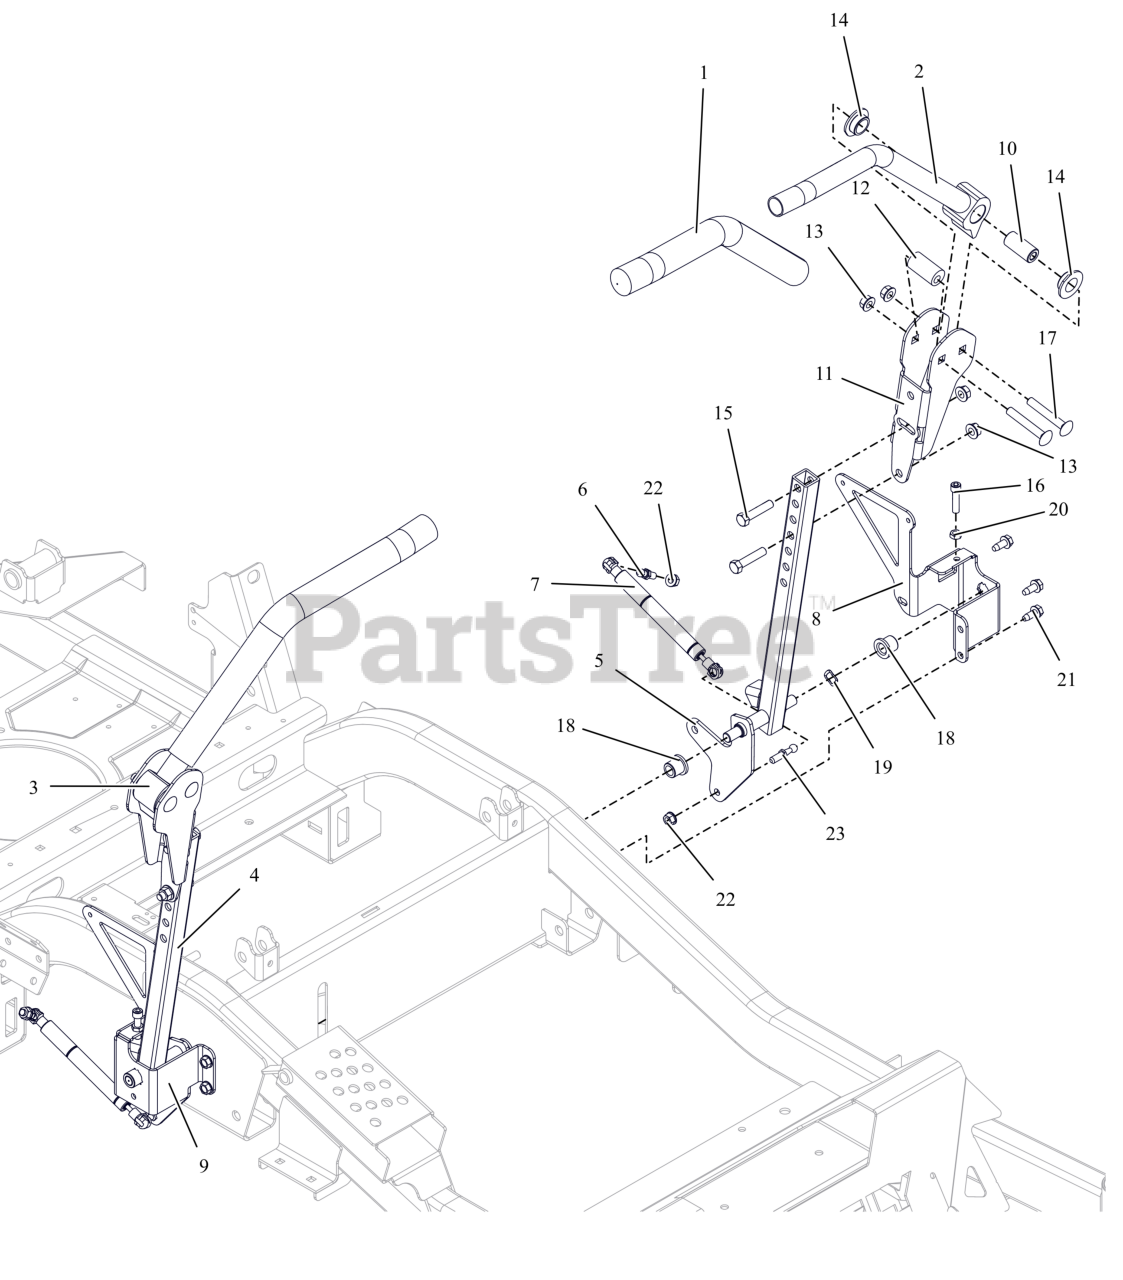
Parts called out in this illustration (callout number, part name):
1	GRIP, HANDLEBAR
2	WLDMT, CONTROL HANDLE (RED)
3	WLDMT, CONTROL HANDLE (RED)
4	WLDMT, STEERING RH (RED)
5	WLDMT, STEERING -LH (RED)
6	STUD- BALL
8	BRKT, STEERING ARM MOUNTING -LH (RED)
9	BRKT, STEERING ARM MOUNTING- RH (RED)
10	SPACER, STEERING ARM
11	BRKT, ADJ UPPER CONTROL ARM (RED)
12	BSHG, ECCENTRIC.406X.875X1.625
13	NUT-LK-TOP-FLG .38-16 ZC120
14	BSHG, FLANGED .762 X 1.48 X .44 IGLIDER
15	BLT, HEX .38-16X1.75 G5 ZCC
16	SCR, SKH .312-18X1.25 GR8 ZC120
17	BLT, RHSSN.38-16X2.50 G5 ZCC
18	BHSG-FLG .500X.750X.750X.125
19	WAVE WASHER .531X.781X.125FH
20	NUT-JAM .312-18 G2 ZCC
21	SCR,TAP .312-18X.75 HWH TR ZCC
22	NUT,LK-CTR-FLG .31-18 GF ZCC
23	STUD-BALL-THREADED
